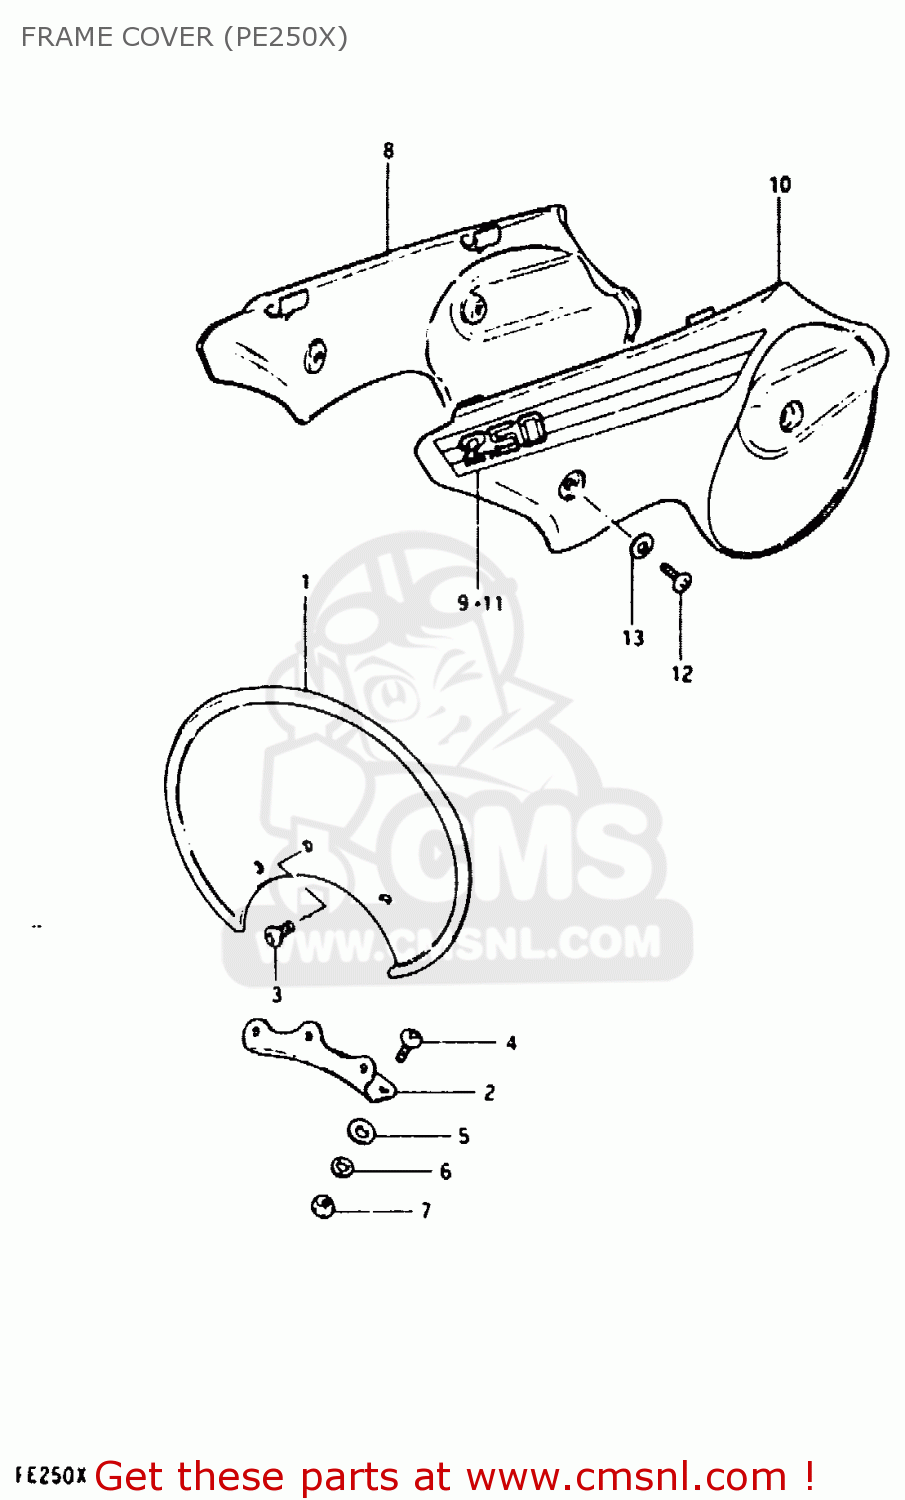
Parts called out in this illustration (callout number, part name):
1	PLATE,NUMBER,FRONT
2	BRACKET
3	CLAMP
4	SCREW
5	SCREW
6	WASHER
7	LOCK WASHER
8	NUT
9	COVER,FRAME,R(YELLOW)
10	TAPE,FRAME COVER
11	COVER,FRAME,L(YELLOW)
12	TAPE,FRAME COVER
13	SCREW
14	SPACER
